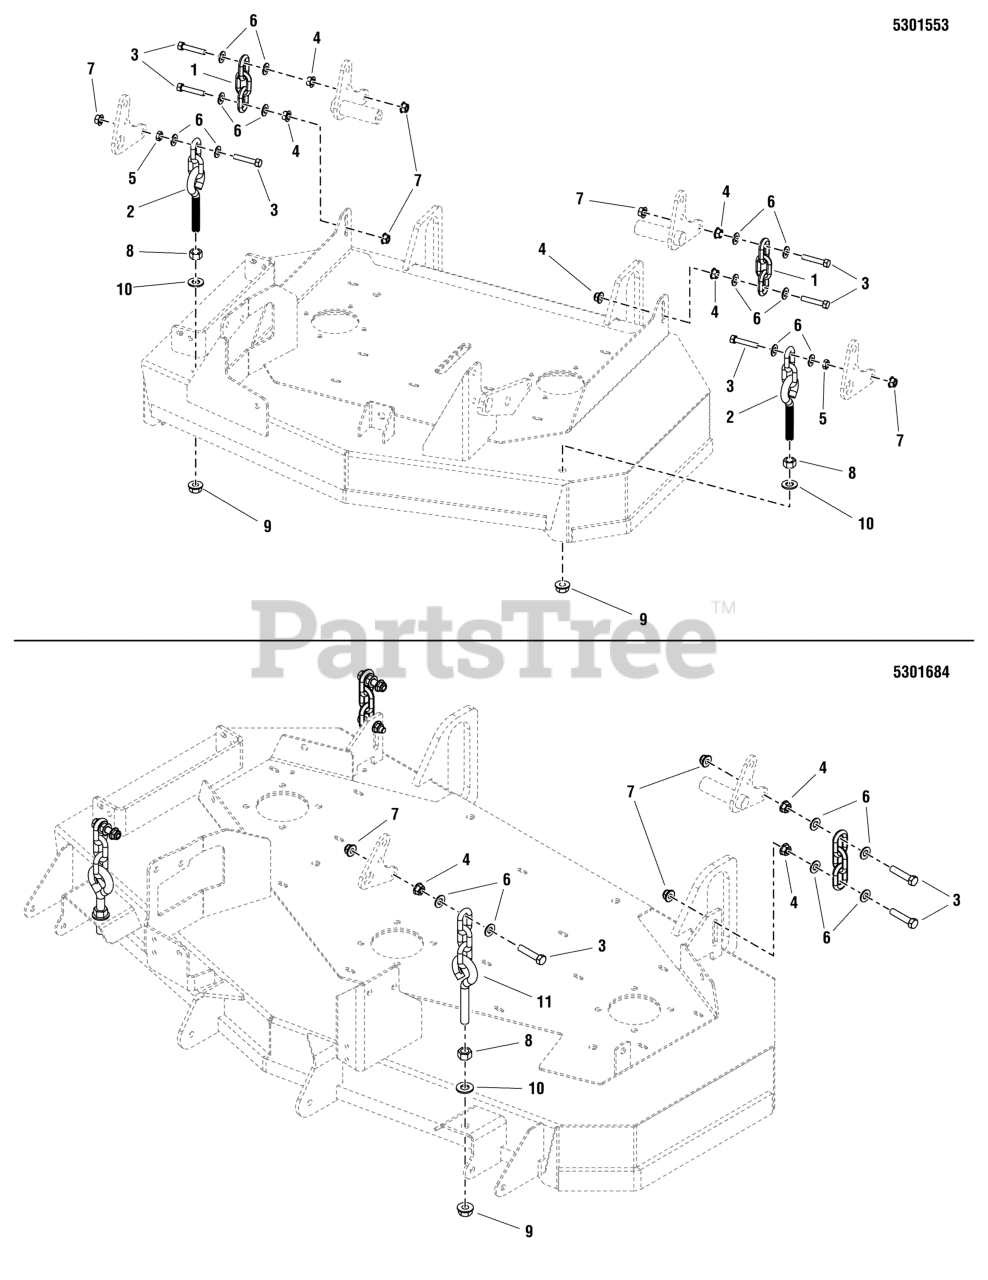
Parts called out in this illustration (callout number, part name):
1	CHAIN, 5/16 GD30, 3 LINKS
2	HANGER, FRONT DECK-2LINK, 5.5" EB
3	BOLT, 3/8-16 X 1-3/4" GD5 CZ
4	NUT, 3/8-16 HEX SERRATED FLANGE
5	NUT, 3/8-16 HEX JAM
6	WASHER, 3/8 SAE
7	NUT, 3/8-16 HEX NYLOCK FLANGE
8	NUT, 1/2-13 HEX
9	NUT, Hex Flange, Nylock, 1/2-13
10	WASHER, 1/2 SAE
11	HANGER, FRONT DECK-3LINK, 5.5" EB
